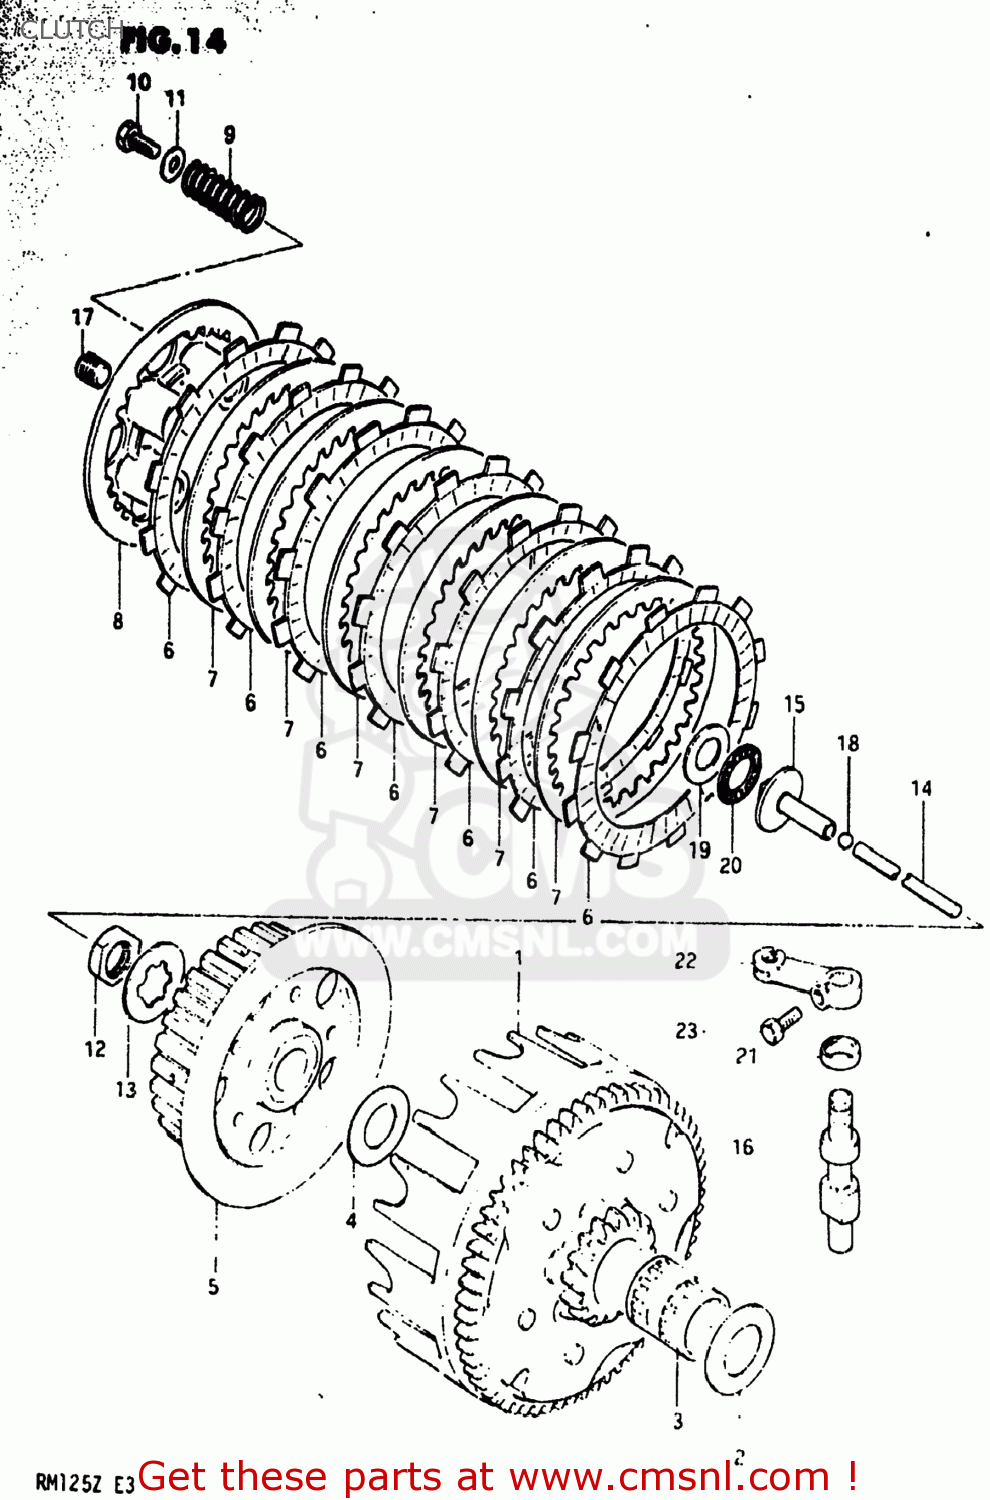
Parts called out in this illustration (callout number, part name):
1	GEAR ASSEMBLY,PRIMARY DRIVE
2	WASHER
3	BEARING(20X25X26)
4	WASHER
5	HUB,CLUTCH SLEEVE
6	PLATE,CLUTCH DRIVE
7	PLATE,CLUTCH DRIVEN
8	DISC,CLUTCH PRESSURE
9	SPRING
10	BOLT(5X16)
11	WASHER (5.5X16X1.2)
12	NUT
13	WASHER,LOCK
14	ROD,CLUTCH PUSH
15	PIECE,CLUTCH PUSH
16	CAMSHAFT,CLUTCH RELEASE
17	SCREW
18	BALL
19	WASHER
20	BEARING(15X28X2)
21	OIL SEAL
22	ARM,CLUTCH RELEASE
23	BOLT, UPPER
